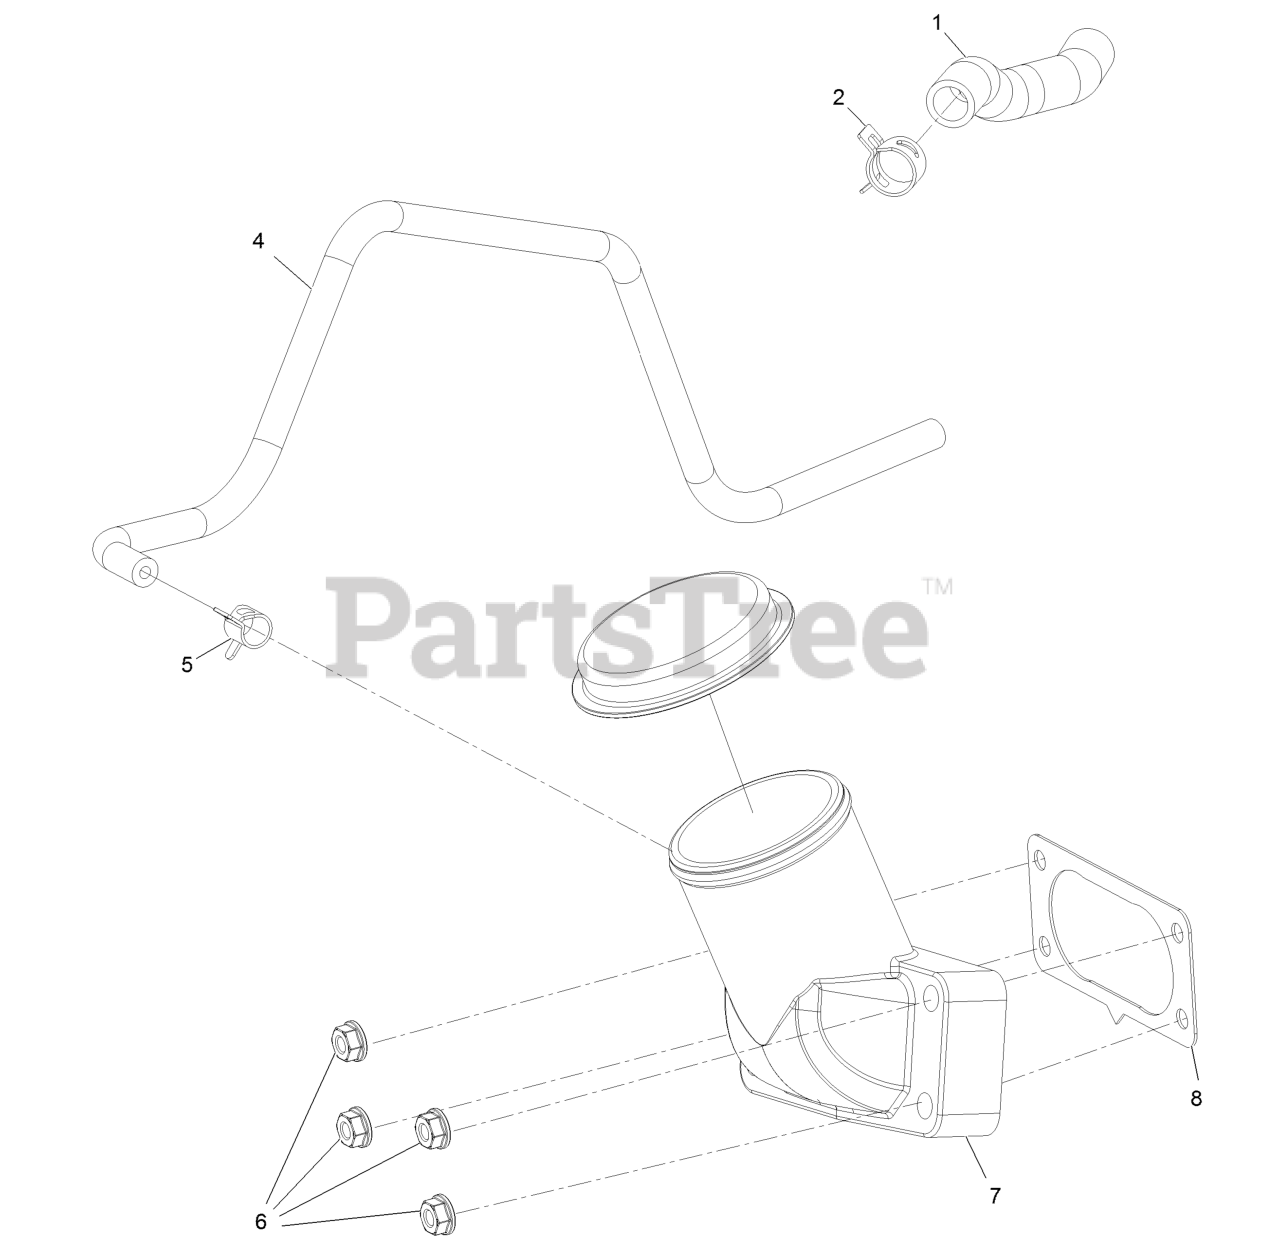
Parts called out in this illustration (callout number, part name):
1	Tube-Breather
2	Clamp-Hose
4	Hose-Fuel
5	Clamp-Hose
6	Nut-Flange
7	Manifold-Intake
8	Gasket-Carburetor
